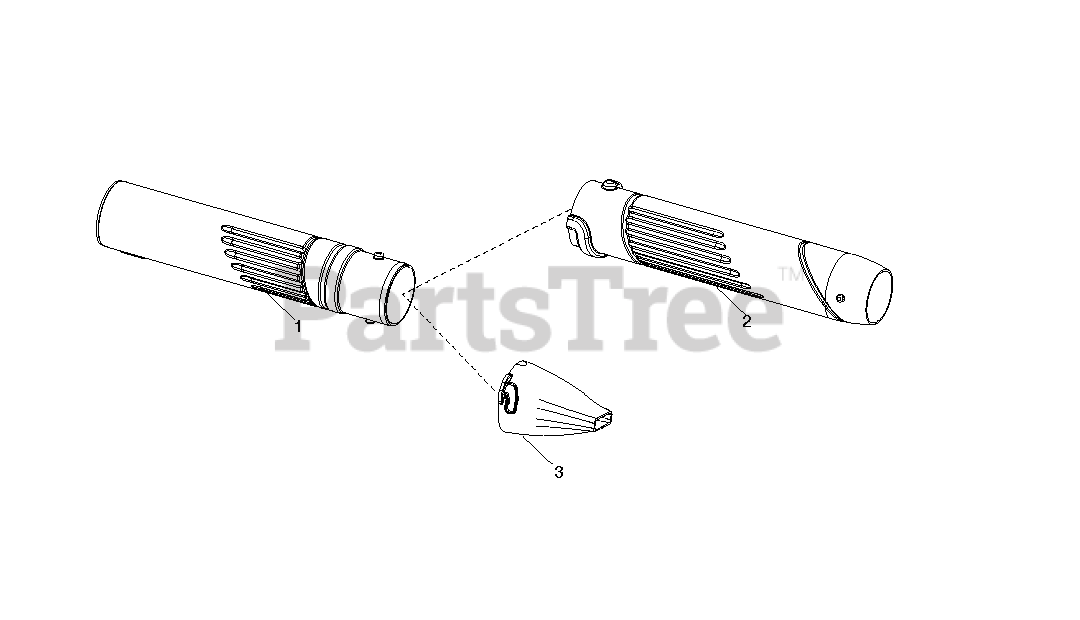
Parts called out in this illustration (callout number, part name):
1	TUBE BLOWER SUPPER W BLACK
2	TUBE BLOWER LOW END BLACK
3	NOZZLE BLACK HI SPEED ADAPTOR
